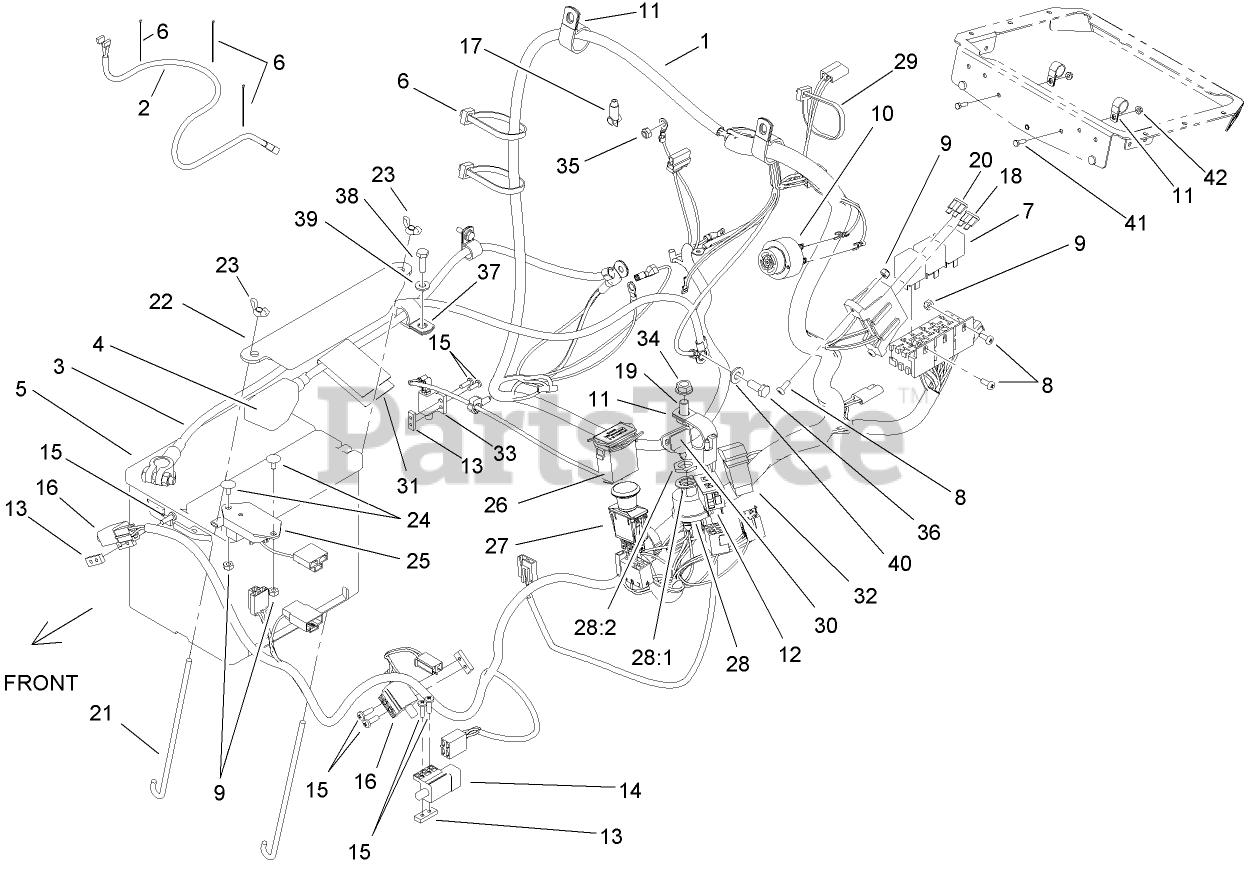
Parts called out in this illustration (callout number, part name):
1	HARNESS-ELECTRICAL, MAIN
2	HARNESS-WIRING, SEAT
3	CABLE-BATTERY, NEGATIVE
4	CABLE-BATTERY, POSITIVE
5	BATTERY-DRY
6	TIE-PLASTIC
9	NUT-LOCK, NI
10	ALARM-TONE, DUAL
11	CLIP-LOOM
12	LAMP-WARNING
13	PLATE-TAPPED
14	SWITCH
15	SCREW-PPH
16	SWITCH-OPEN, NORMALLY
17	CAP-INSULATOR, RED
18	FUSE-40 AMP
19	SCREW-HH
20	FUSE-BLADE, 30 AMP
21	Bolt-Holddown
22	HOLDDOWN-BATTERY
23	WINGNUT
24	BOLT-CARR
25	MODULE-DELAY, SEAT
26	METER-HOUR
27	SWITCH-PTO
28	SWITCH ASM
28:1	NUT-HH
28:2	WASHER-TOOTH, INTERNAL
29	TIE-CABLE
30	KEY-IGNITION
31	DECAL-INSTRUCTIONS, CHARGING
32	SWITCH-ROCKER
33	SWITCH-CLOSED, NORMALLY
34	NUT-HHF, WHIZ
35	NUT-LOCK
36	SCREW-HH
37	CLIP-LOOM
38	SCREW-HH
39	WASHER-FLAT
40	WASHER-PLAIN
41	SCREW-HH
42	NUT-HF
